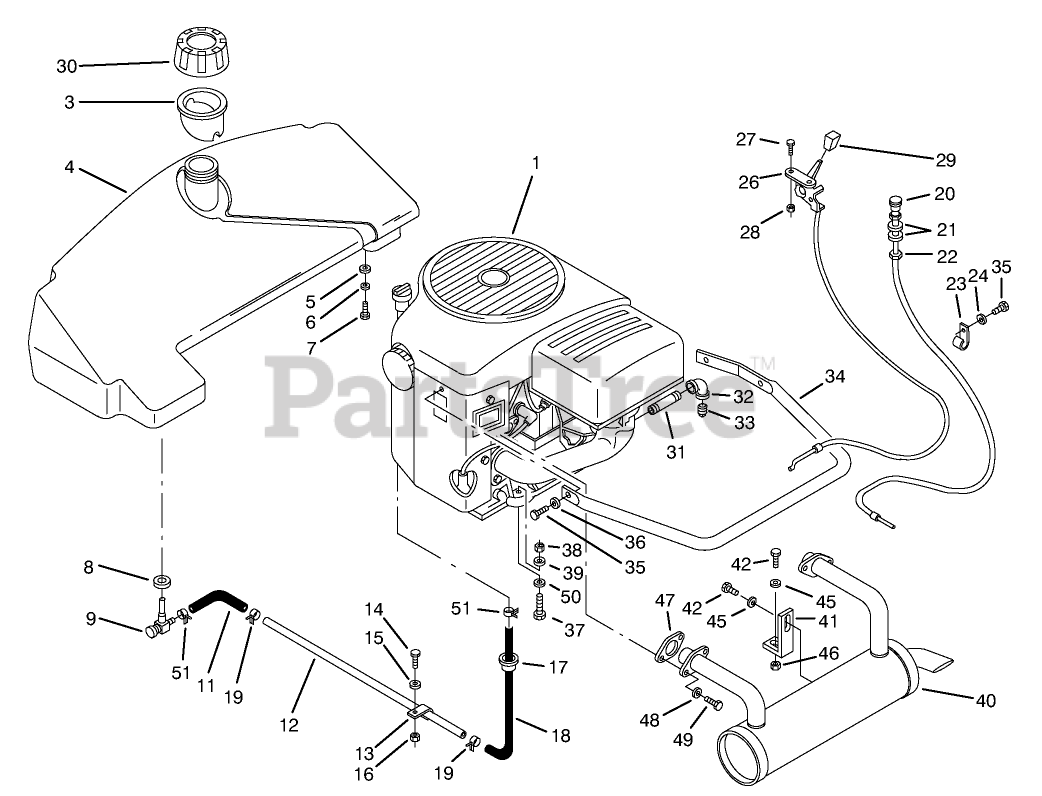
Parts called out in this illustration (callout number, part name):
1	Engine-16HP Model P216V-1/11103-D
3	FUNNEL-FUEL TANK
4	Fuel Tank Assembly (Incl. Ref. #8-9)
5	WASHER-FLAT
6	WASHER-LOCK
7	SCREW-HH
8	BUSHING
9	VALVE-FUEL
11	HOSE-FUEL
12	TUBE FUEL LINE
13	J-CLIP
14	SCREW-HH
15	WASHER-PLAIN
16	NUT-LOCK, NI
17	BUSHING-NYLON 1.093
18	Hose-18" Fuel
19	CLAMP-FUEL LINE
20	CONTROL-CHOKE
21	WASHER-FLAT
22	NUT-HEX PALNUT
23	CLIP
24	WASHER-FLAT
26	CONTROL-THROTTLE
28	NUT-LOCK, NI
29	KNOB-CONTROL
30	GAS CAP ASM
31	NIPPLE-3/8 X 2.5
32	ELBOW 3/8 90 DEG
33	Plug
34	GUARD-AIR CLEANER
35	SCREW-HH
36	WASHER-LOCK
37	SCREW-HH
38	NUT-LOCK, NI
39	WASHER-PLAIN
40	EXHAUST-MUFFLER
41	BRACKET-MUFFLER
42	SCREW-HH
45	WASHER-PLAIN
46	NUT-LOCK, NI
47	GASKET
48	WASHER-LOCK
49	SCREW-HSH
50	WASHER
51	CLAMP-HOSE
